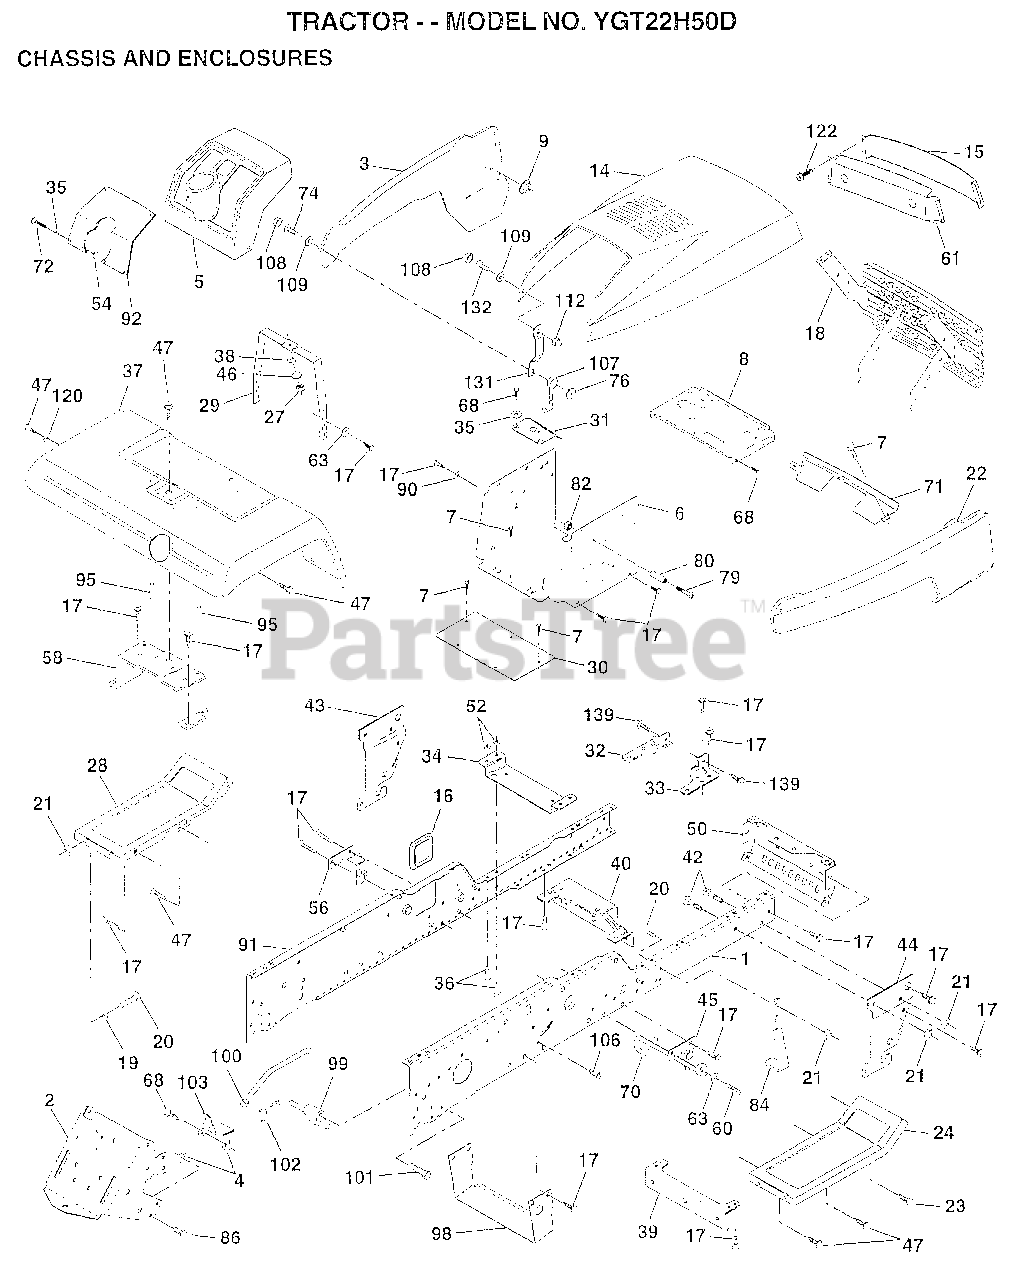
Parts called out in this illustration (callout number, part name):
1	"RAIL,FRAME RH"
2	DRAWBAR GT
3	"PANEL ASM-SIDE,LH"
4	NUT.7/16
5	DASHBOARD BLACK
6	DASH LOWER
7	SCREW
8	SUPPORT.DASH.BTRY
9	PAL NUT LT
14	"HOOD, YARD PRO"
15	LENS.BAR.CLEAR
16	COVER ACCESS
17	SCREW
19	WASHER
20	BOLT
22	"PANEL ASM SIDE,RH"
23	SCREW GTV
24	FOOTREST.RH.LT/GT
28	FOOTREST PNT LH
29	DASH.SUPT.YP/HUSQ
30	SADDLE.HYDRO.95
31	BRKT SUPT 1-PC VG
32	BKRT.PIVOT.CHASSIS.LH
33	BKRT.PIVOT.CHASSIS.RH
34	BRACKET.ENG.SUPT.
35	WASHER
36	BOLT
37	"FENDER WS,FTK"
38	LOCKWASHER
39	BRACKET.AXLE.FRT.
40	"BRKT SUPPORT,AXLE"
43	BRACKET.SUS.FT.LH
44	BRACKET.SUS.FT.RH
45	BRACKET.SUSP.RH.
46	WASHER PM
47	SCREW LT
50	"BRKT CHASSIS,FRNT"
56	BRACKET.SUSP.LH.
58	BRKT.ASM.FENDER
60	SCREW
61	BEZEL.1 PC
63	WASHER
68	SCREW LT
70	GUIDE.BELT.MID.SP
72	SCREW
74	SCREW
76	WELDNUT
79	SCREW
80	SPACER LT
84	STOP.OVER.CENTER
86	BOLT
90	LOCKWASHER
91	"RAIL FRAME,LH"
95	NUT-PUSH YT
98	BRACKET SKID CHAS
99	ROD BYPASS
101	SCREW LT
102	RETAINER M
103	LOCK BYPASS BRKT
107	HOOD LATCH T
108	SNAP CAP LT
109	WASHER LT
112	ACORN NUT RB
120	WASHER HYT
122	SCREW.HEX.WS.HD
131	BKT.SPT.HOOD/PANL
132	SCREW.10-24X3/8.
139	BOLT.SHOULDER.5/16-18
